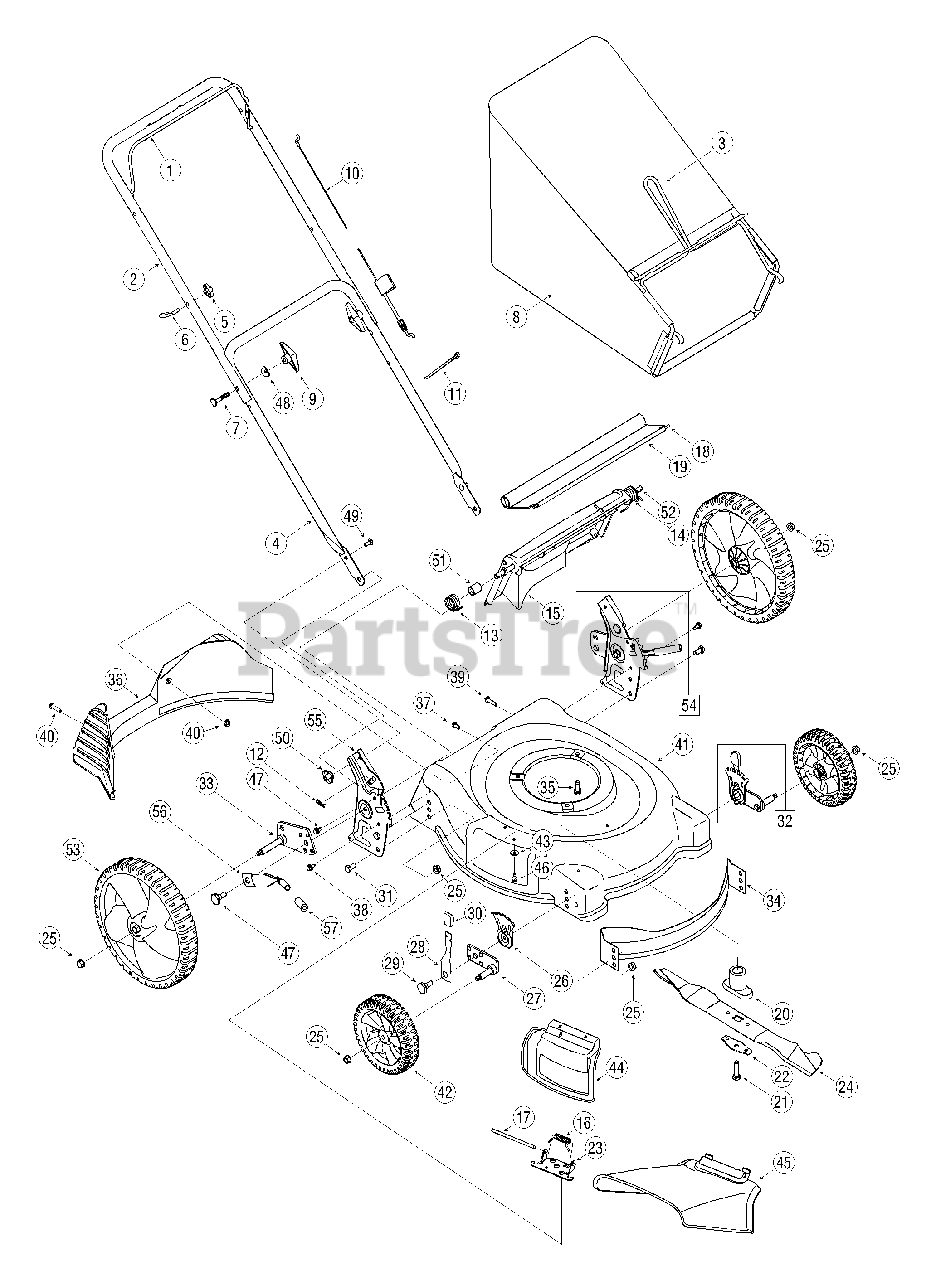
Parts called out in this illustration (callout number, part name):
5	Wing Nut
6	Rope Guide
7	Carriage Bolt 5/16-18 x 2"
8	Grass Bag
9	Handle Knob
10	Control Cable 40"
11	Cable Ties
12	Hairpin Clip
13	Torsion Spring - RH
14	Torsion Spring - LH
15	Grass Bag Door
16	Torsion Spring
17	Hinge Pin
18	Wire Rod
19	Trail shield
20	Blade Adapter
21	Hex Cap Screw 3/8-24 x 2.5
22	Blade Bell Support
23	Chute Deflector Adapter
24	Blade: 21" Mulching
25	Flange Lock Nut 3/8-16
26	Height Adjustment Plate
27	Pivot Bar Assembly - RH
28	Spring Lever
29	Shoulder Screw
30	Spring Lever Knob
31	Hex Screw 3/8-16 x 0.75
32	Front Height Adjuster Assembly - RH
33	Pivot Bar Assembly - RH
34	Front Baffle
35	Hex Washer Screw 3/8-16 x 1.0
36	Rear Baffle 21" Rd.
37	Machined Screw 1/4-20
38	TT Screw 1/4-14 x.625
39	Hex Screw 1/4-15
40	Flange Lock Nut 1/4-20
43	Bell Washer.265 ID x.75 OD
44	Hinged Mulch Plug Assembly
45	Side Discharge Deflector
46	Screw 1/4-20
47	Hex Cap Screw 3/8-16 x 1.0
48	Shoulder Washer.320 ID x.930 OD
49	Hex Carriage Screw 1/4-20
50	Wing Nut
51	Spacer.375 O.D. x.50 I.D. x 1.02"
52	Chute Door Pivot Rod
53	Rear Wheel: 8-Spoke Bar Gray 12 x 2
54	Handle Bracket Assembly - LH
55	Handle Bracket - RH
56	Spring Lever
57	Spring Lever Knob
